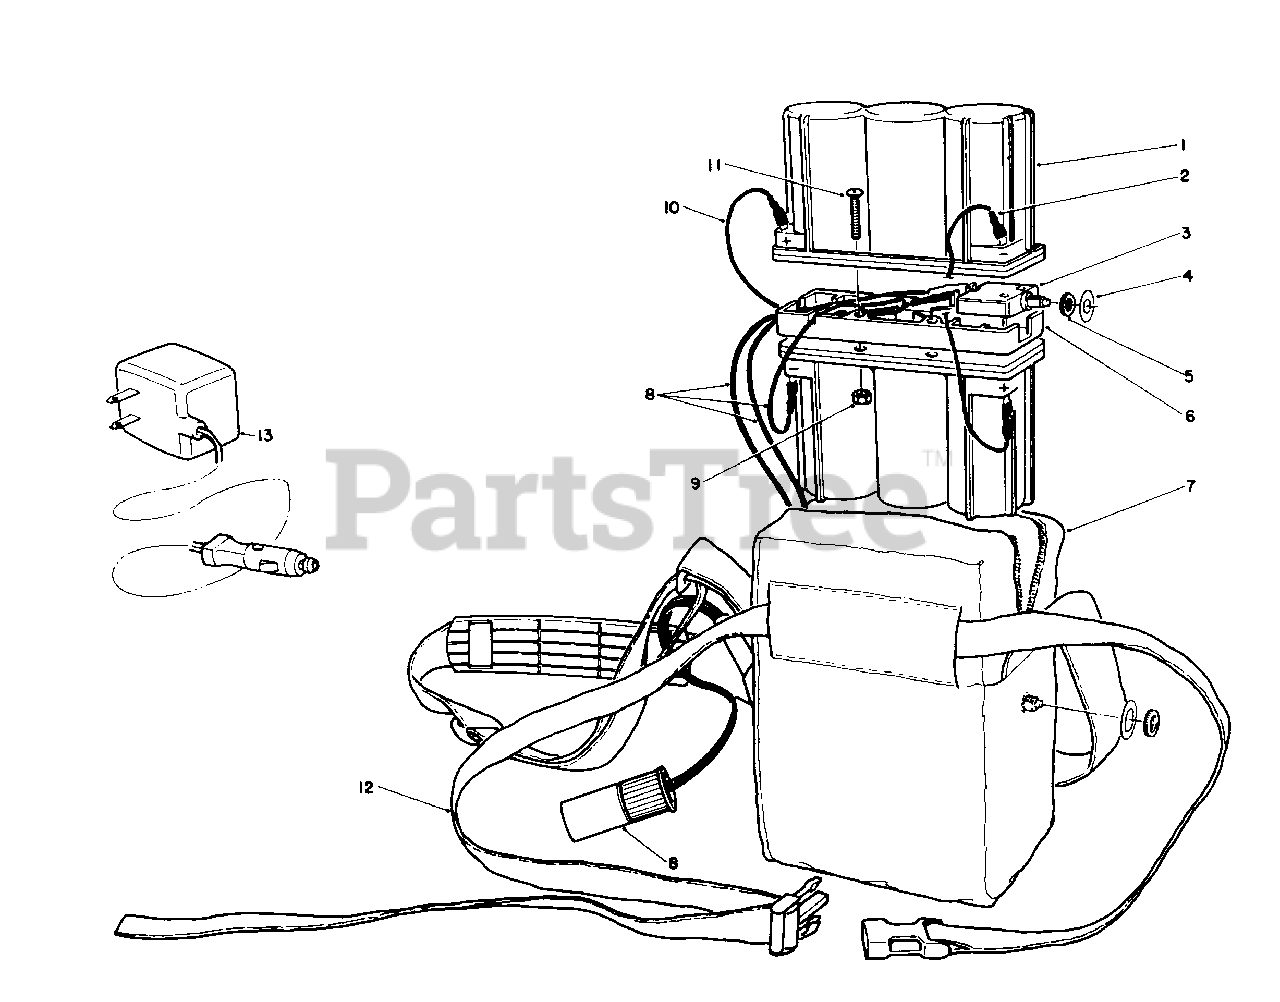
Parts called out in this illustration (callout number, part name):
1	Battery-6 Volt
2	Wire-Battery
3	Circuit Breaker
4	Plate-Breaker, Circuit
5	Nut-Knurled
6	Spacer-Battery
7	Pack-Soft
8	Cord-Battery
10	Wire-Breaker, Circuit
11	Screw-Phillips, Pan Hd.
13	Charger-12 Volt
